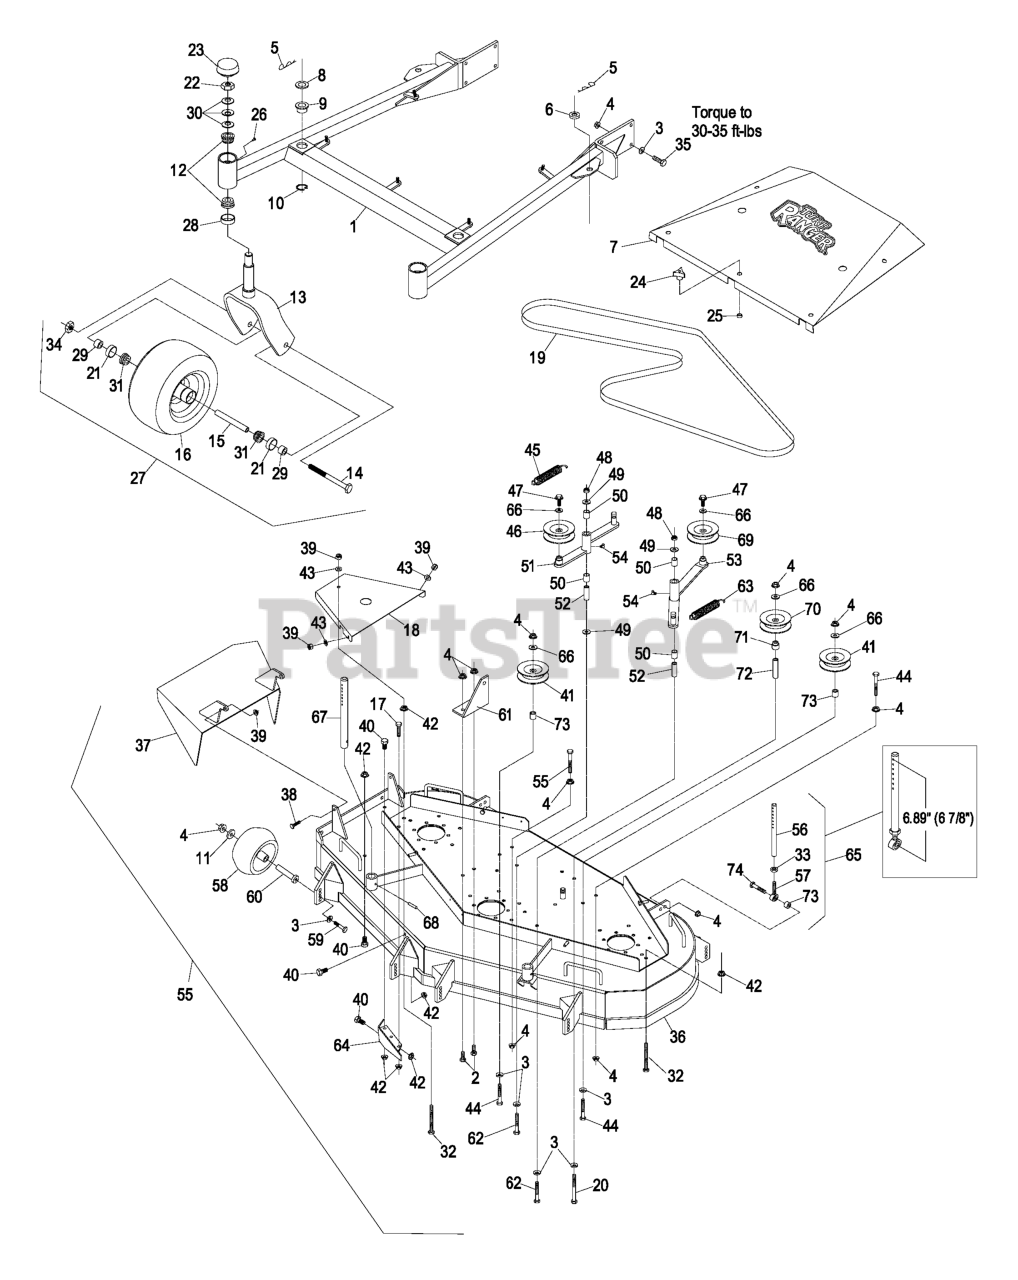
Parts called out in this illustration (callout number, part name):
1	ASM,524 FMD DK SUPPORT,SE
2	SCREW-HH
3	WASHER-BELLEVILLE
4	NUT-HHF, WHIZ
5	PIN,HAIR COTTER
7	KIT,SHIELD TR W/ DECALS F
8	SPACER-DECK SUPPORT
9	BUSHING-DECK
10	RING-RETAINING
12	Cone-Bearing Tapered Roller
13	WLD, CASTER FORK
14	SCREW-HH
15	SPACER,FRONT CASTER
17	SCREW-HH
18	SHIELD,BELT SIDE FMD524
19	BELT,BLADE DRIVE FMD524
20	SCREW-HH
21	SEAL-CASTER
22	NUT-LOCK, NI
23	CAP-GREASE
24	KNOB-3 PRONG
28	SEAL-GREASE
29	SPACER-BEARING
30	WASHER-BELLVILLE
31	BEARING-CONE, TAPERED ROLLER
32	BOLT,TAP HH
33	NUT-HEX
34	NUT-HEX
35	SCREW-HH
38	SCREW-HH
39	NUT-LOCK, NI
40	SCREW-HH
41	IDLER,PULLEY
43	WASHER-FLAT
44	BOLT-CARR
45	SPRING-EXTENSION
46	IDLER,PULLEY
47	SCREW-HHF
48	NUT-LOCK, NI
49	WASHER-FLAT
50	SLEEVE-BEARING
51	ASM,IDLER ARM
52	BUSHING-PIVOT, IDLER
53	ASM,IDLER ARM
54	FITTING-GREASE, 90 DEG
55	Complete Deck Assembly
56	LINK,SUPPORT
57	BALLJOINT
58	ROLLER-SCALP, ANTI
59	SCREW-HH
60	BUSHING-ROLLER
61	BRACKET,SPRING ANCHOR
62	SCREW-HH
63	SPRING-EXTENSION
64	WLD,BAFFLE DISCHARGE
66	WASHER-FLAT
67	ROD,DECK SUPPORT
69	PULLEY-IDLER
70	PULLEY-IDLER
71	BUSHING,IDLER
72	SPACER-ANCHOR, CLUTCH
74	SCREW-HH
